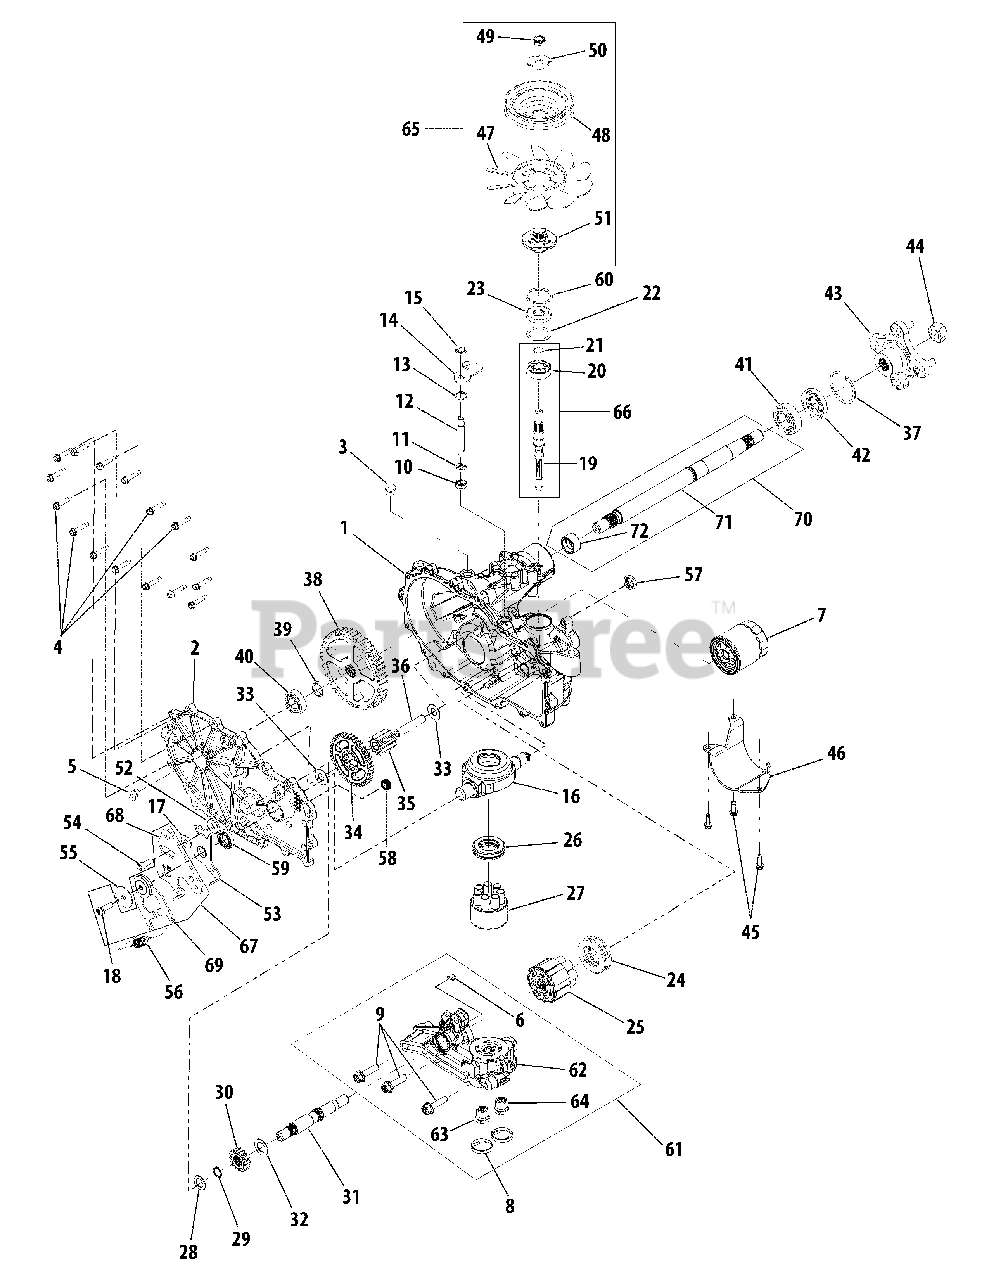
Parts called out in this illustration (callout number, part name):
1	Housing Assembly, Main
2	Side Cover Assembly
3	Plug, Straight Thread
4	Screw, Hex Flange
5	Plug, Straight Thread
6	Plate, Bypass
7	Filter, Oil
8	Seal, Plug
9	Screw, Hex Cap, 3/8-16 x 1.5 Patched
10	Seal, Lip
11	Ring, Retaining, .375 Ext.
12	Rod, Bypass
13	Ring, Retaining, .75 Int.
14	Arm, Bypass
15	Ring, Retaining, .375 Ext.
16	Swashplate, Trunnion
17	Washer, .34 x .88 x .06
18	Screw, Patch, 5/16-24 x 1
19	Shaft, Input
20	Bearing, Ball
21	Ring, Retaining
22	Washer, 1.23 x 1.56 x .04
23	Seal, Lip
24	Bearing, Thrust
25	Block Assembly, Cylinder
26	Bearing, Thrust
27	Block Assembly, 7 Piston
28	Washer, Flat, 5/8 x 1.0 x .05
29	Ring, Retaining
30	Gear, 16T
31	Shaft, Motor
32	Washer, .72 x 1.16 x .04
33	Washer, HT, .5 x 1.0 x .03
34	Gear, 43T
35	Gear, 11T
36	Pin, Jackshaft
37	Ring, Retaiining, 2.06 Int
38	Gear, 54T
39	Spacer, .75 x 1.0 x .257
40	Bearing, Ball
41	Bearing, Ball
42	Seal, Lip
43	Kit, Hub, 4 Bolt
44	Nut, Hex Lock, 3/4-16
45	Screw, Hex Cap, 1/4-20 x .75
46	Guard, Filter
47	Fan, 7"
48	Pulley Disc -
49	Nut, Hex Lock, 1/2-20
50	Washer, Slotted
51	Hub,
52	Spacer, .32 x 1.005 x .179
53	Arm, Neutral
54	Screw, Patch, 5/16-24 x 1
55	Washer, .343 x 1.5 x .062
56	Spring, Extension
58	Seal, Plug
61	Kit, Center Section
65	Kit, Fan/Pulley
66	Kit, Input Shaft
67	Kit, Return Bidirectional
70	Kit, Axle Shaft
